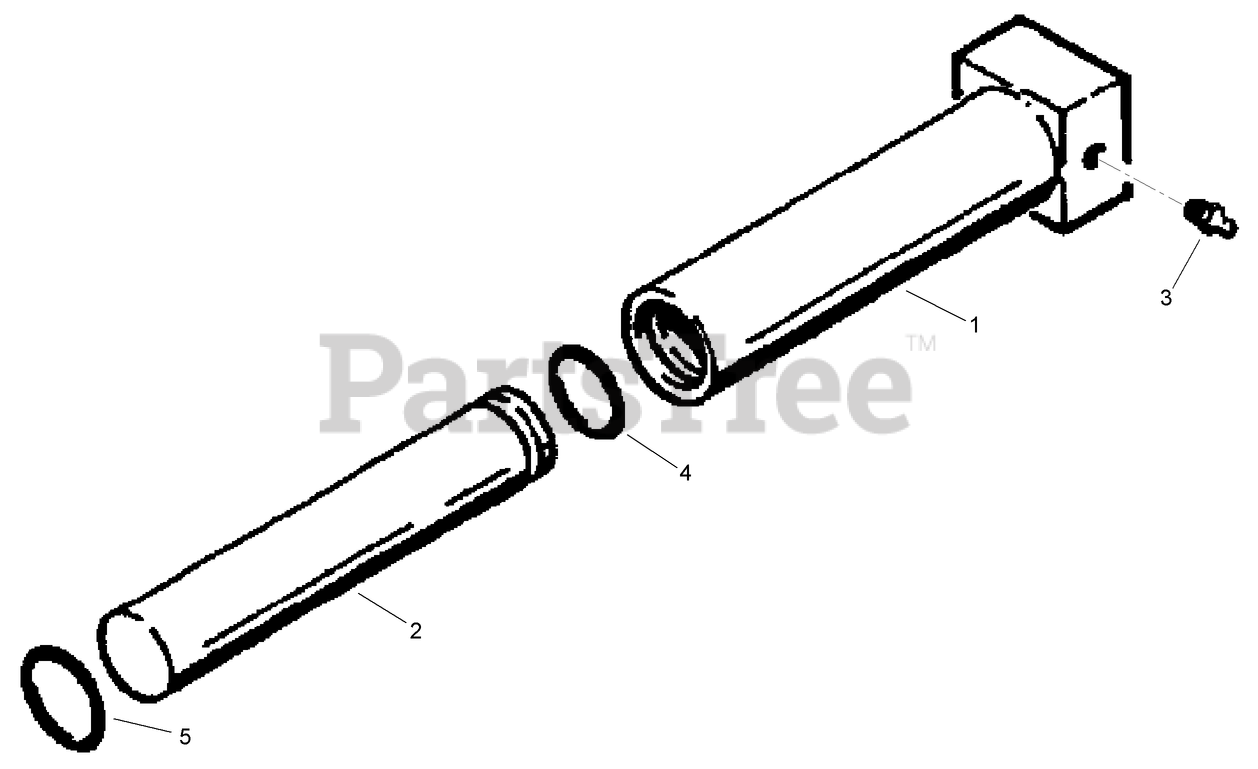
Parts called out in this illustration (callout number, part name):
1	Tube
2	ROD - Piston
3	FITTING-LUBE, STRAIGHT
4	O-RING - 3/4 x 1 Class 5
5	O-RING - 1 ID x 1/16
